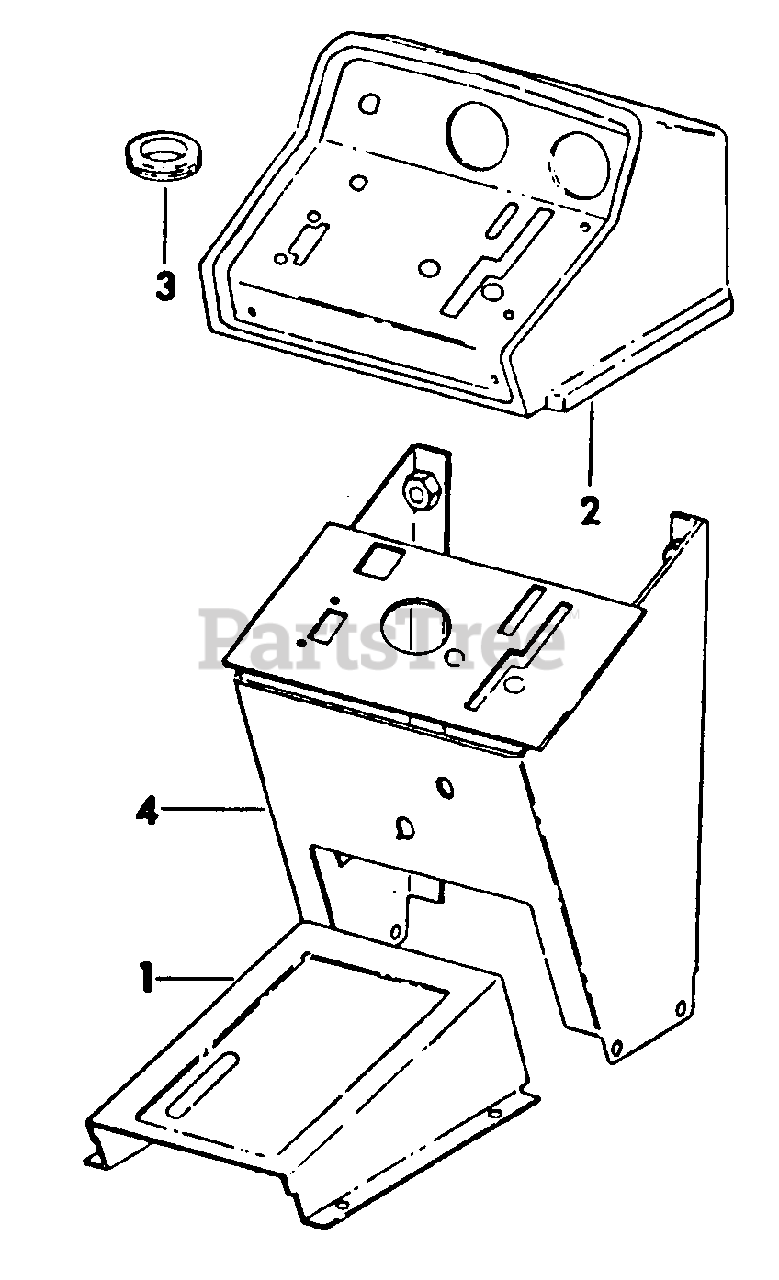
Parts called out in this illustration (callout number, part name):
1	Cover w/Product Graphic
2	Cowl, Instrument Panel
3	Grommet, Instrument Panel
4	Pedestal Assy, Instrument Panel
